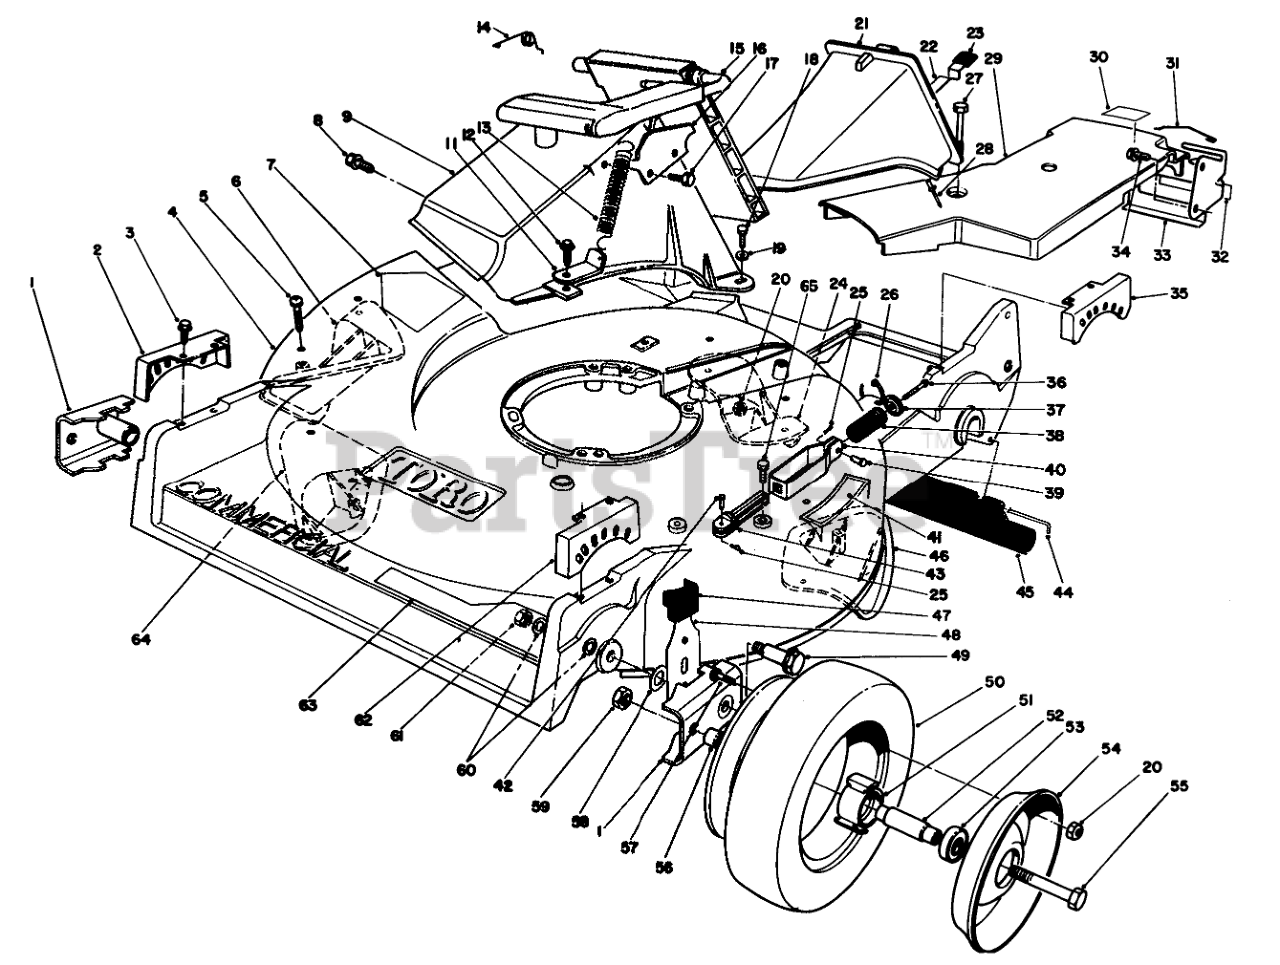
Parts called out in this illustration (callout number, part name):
1	ARM-PIVOT, FRONT
2	QUADRANT-FRONT, RH
3	SCREW-HWHTF
4	Housing-Commercial (Incl. Ref. #7)
5	SCREW-PPH
6	KICKER
7	DECAL-DANGER
8	SCREW AND WASHER ASM
9	DISCHARGE TUNNEL
11	Bracket-Spring
12	SCREW-HWH
13	SPRING-DOOR
14	RETAINER-DOOR
15	DOOR ASSEMBLY
16	DOOR LATCH PLATE
17	SCREW-PLASTITE
18	SCREW-HH
19	WASHER-FLAT
20	NUT-LOCK, NI
21	Plug-Discharge (Incl. Ref. #22, 23, & 28)
22	LATCH-PLUG, DISCHARGE
23	GRIP-LATCH
24	KICKER
25	PIN-COTTER
26	TIE-CABLE
27	SCREW-HHFTF
28	RIVET-HEAD, FLAT
29	BELT COVER (MACHINED)
30	LABEL-GREASE
31	RETAINER-CABLE
32	DECAL-POSITION, GEAR
33	BRACKET-ADJUSTMENT, TRACTION
34	SCREW-HWHTF
35	QUADRANT-REAR, LH
36	SCREW-HWHTF
37	RETAINER-SPRING
38	SPRING
39	PIN-CABLE
40	Bracket-Spring
41	STEP PAD DECAL
42	PIN-SPRING
43	GUIDE-SPRING
44	ROD-SHIELD
45	SHIELD-TRAILING
46	KICKER
47	KNOB-ARM
48	FRONT SPRING ARM ASM
49	WHEEL BOLT
51	HUB-BEARING
52	SPACER-BEARING
53	BEARING-WHEEL
54	Wheel-Half
55	SCREW-HH
56	SPACER-WHEEL
57	SCREW-HH
58	WASHER-THRUST
59	NUT-LOCK, CONE
60	WASHER
61	Nut
62	QUADRANT-FRONT, LH
63	DECAL - RECYCLER
64	KICKER
65	SCREW-HH
